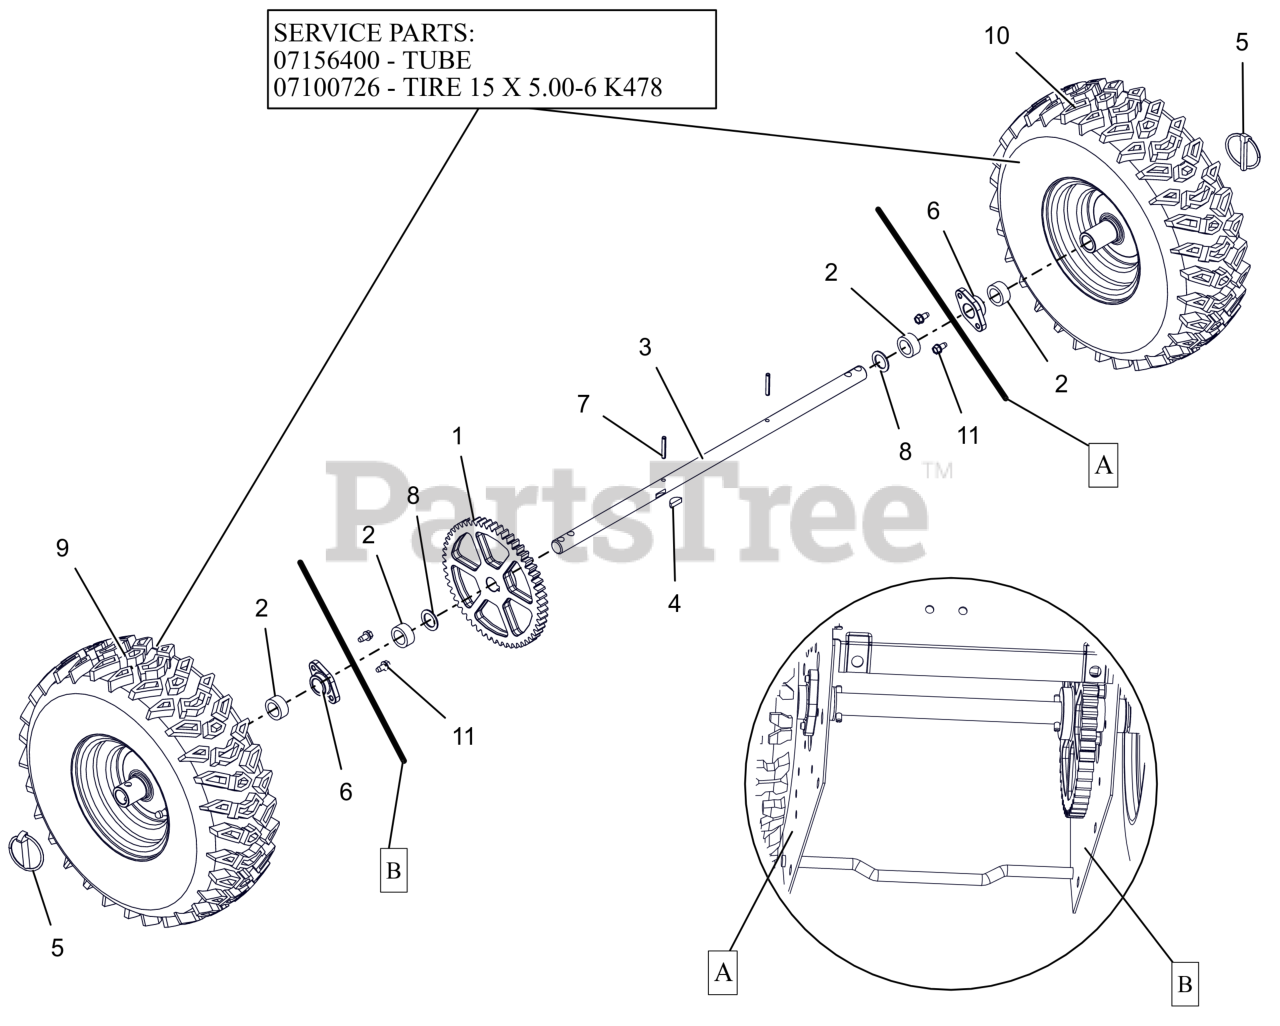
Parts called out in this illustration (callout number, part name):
1	SPUR GEAR, 54T .75ID X 6.75PD
2	BSHG-SLV .766 X 1.125 X .500
3	AXLE, COMPACT
4	KEY-WDRF .25X.750X.313 SAE91
5	PIN-LOK .31X1.75
6	BSHG .75X1.125X.65
7	PIN-ROLL .188X1.25
8	WSHR, FLT .754X1.125X.062 ZCC
9	TIRE/WHEEL,RH 15X5.00-6 PIN T2
10	TIRE/WHEEL,LH 15X5.00-6 PIN T2
10	TUBE 15 X 5.00-6
10	TIRE, 15X5.00-6 K478
11	SCR-TAP .25-20X.50 HWH ZCC
